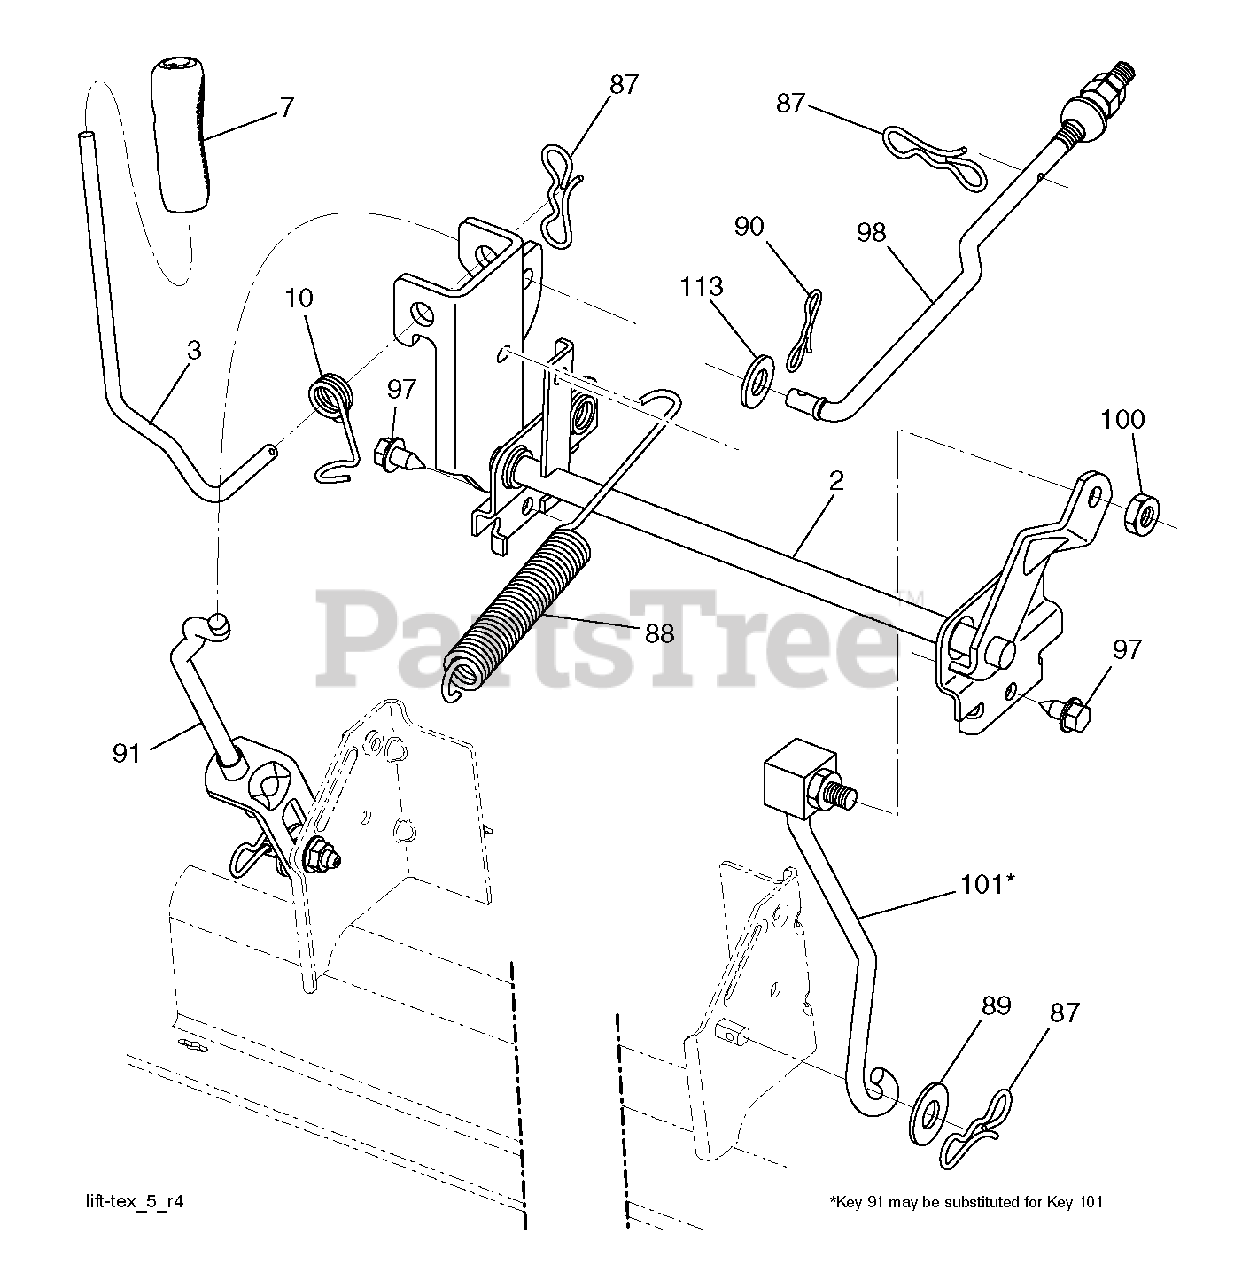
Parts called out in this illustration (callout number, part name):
2	SHAFT.ASM.CROSS.LIFT
3	LEVER.LIFT.HANDLE.LT
7	GRIP.LEVER.
10	SPRING.TORSION.LIFT.HANDLE
87	PIN.COTTER.7/16.BOW TI
88	SPRING.LIFT.ASSIST
89	WASHER.CLEAR.ZINC
90	PIN.COTTER.5/16.BOW TI
91	LINK.ASM.LIFT.REAR
97	SCREW, 3/8-16X3/4
98	LINK.ASM.SUSP.FRONT.MWR.10.5
100	LOCKNUT
101	LINK.ASM.LIFT.FIXE.38/42/46"
